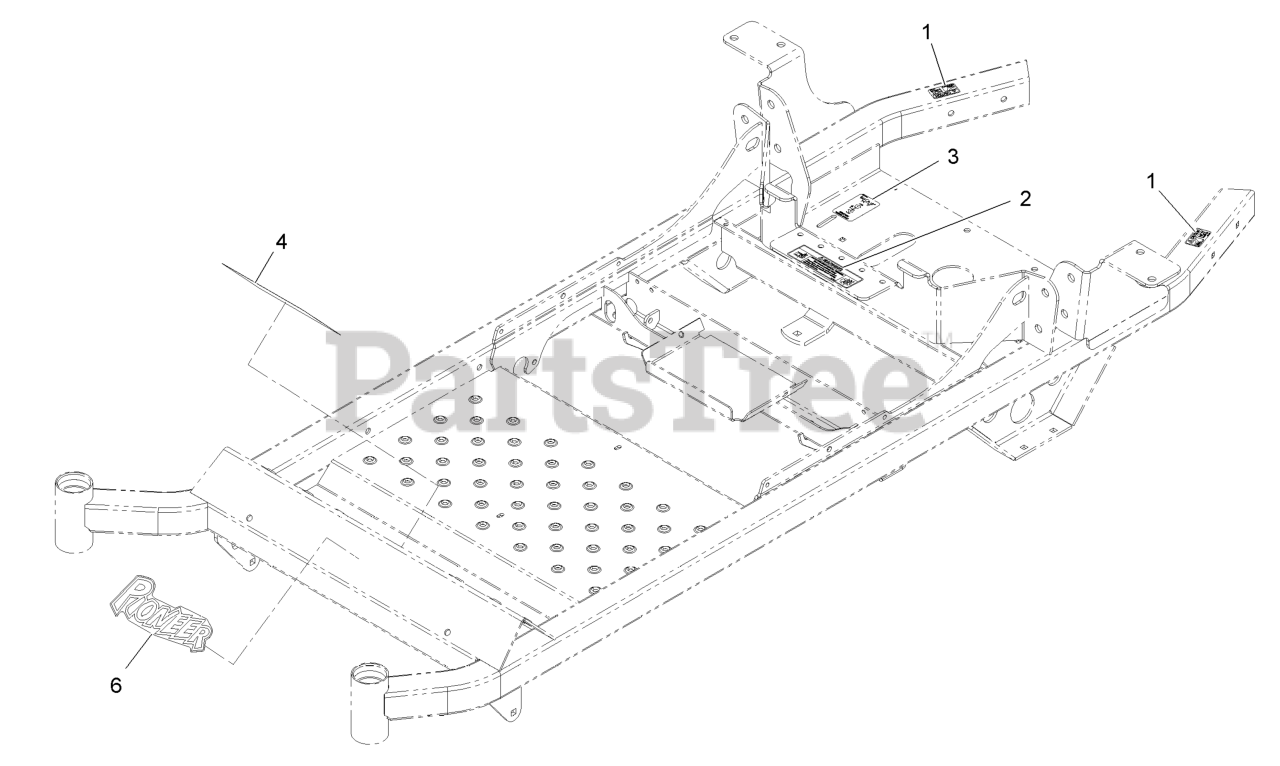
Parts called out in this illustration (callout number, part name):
1	DECAL-CAUTION
2	DECAL,BELT DRIVE
3	DECAL,DRIVE RELEASE
4	DECAL-SLOPE
6	DECAL-PIONEER LOGO
